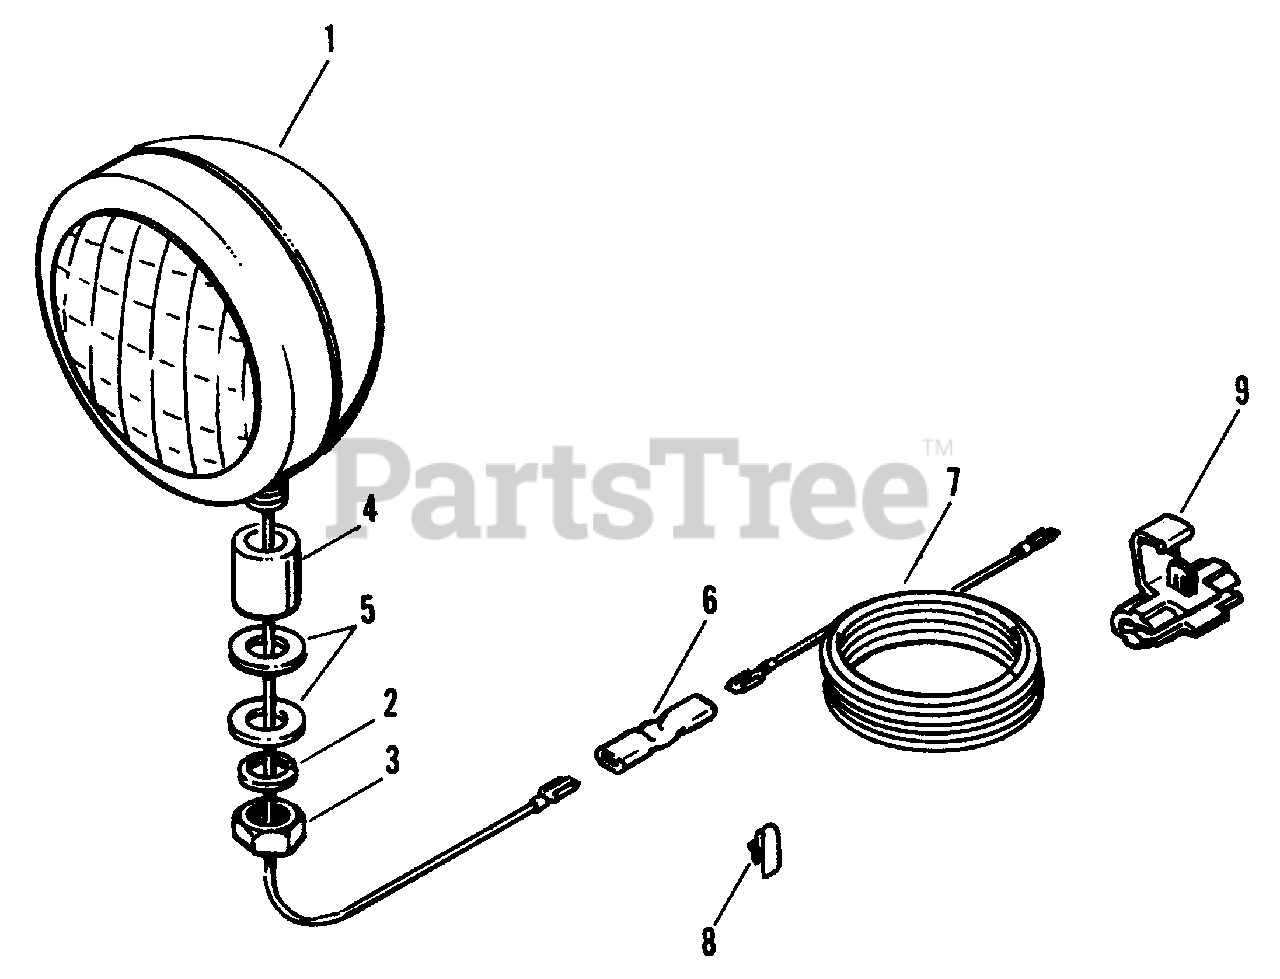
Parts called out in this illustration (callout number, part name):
1	Lamp Assembly
2	Lock Washer, 1/2"
3	Hex Nut, Full, 1/2"-13
5	Plain Washer, 7/16"
6	Connector
8	Wire Clip
